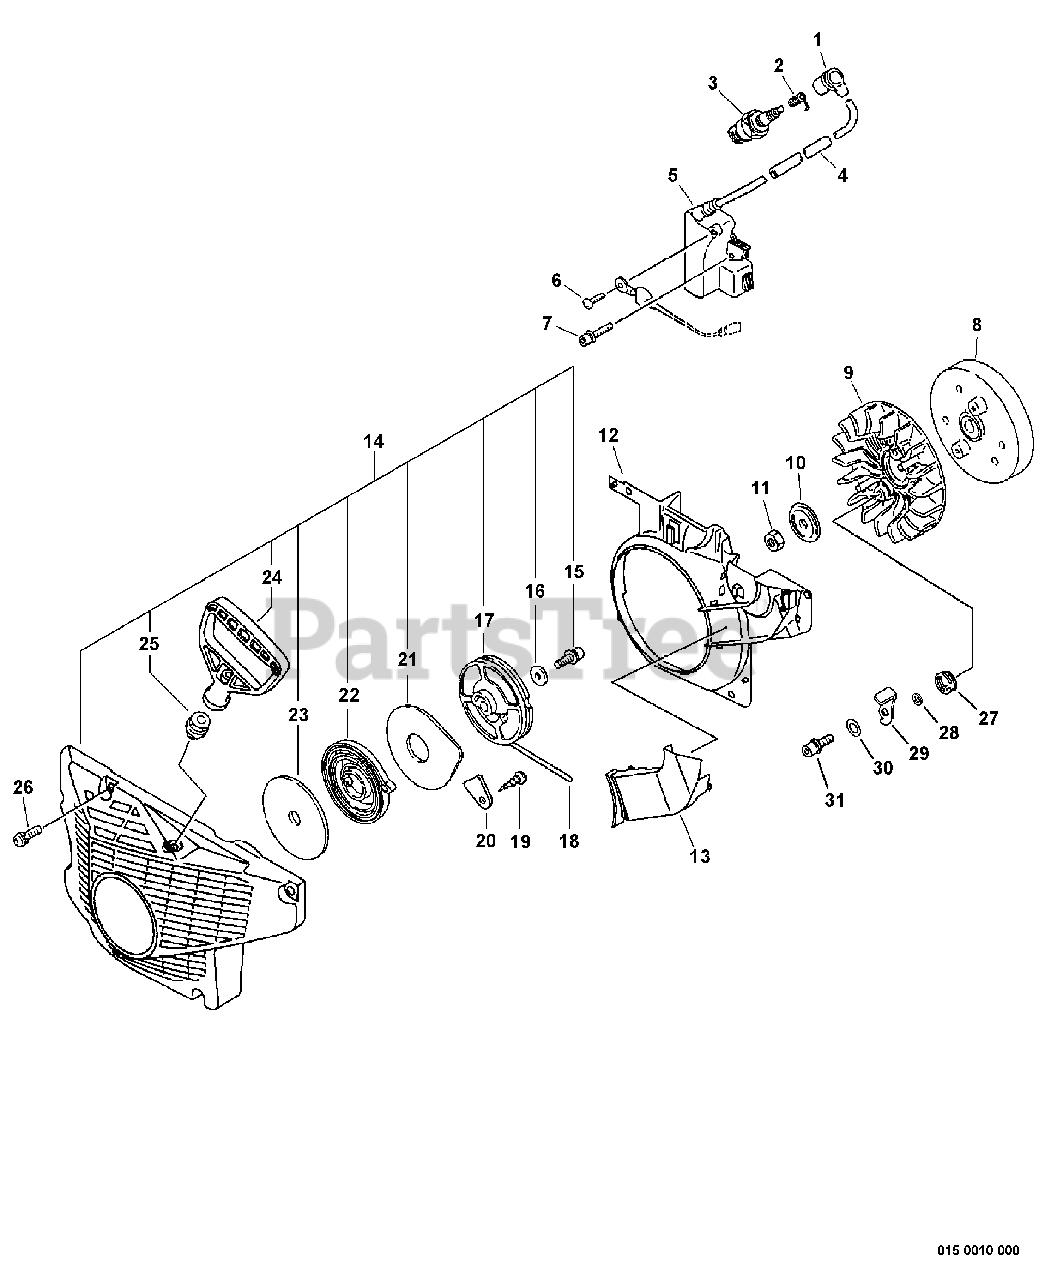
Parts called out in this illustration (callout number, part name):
1	CAP, SPARK PLUG
2	TERMINAL, SPARK PLUG
3	SPARK PLUG - BPM7A
3	SPARK PLUG - BPMR7A
5	COIL, IGNITION
6	SCREW 4×8
7	BOLT 4×20
8	FLYWHEEL
10	WASHER 8.2×31×0.8
12	COVER, FAN
13	DUCT, AIR
14	STARTER ASSY
15	BOLT 5×14
16	WASHER 5.5×12×0.8
17	REEL, ROPE
18	ROPE, STARTER 4.0×950
19	SCREW 4×8
20	PLATE, EYE
21	PLATE, STARTER
22	SPRING, RECOIL
23	PLATE, STARTER
24	GRIP, STARTER
25	GUIDE, ROPE
26	BOLT 5×20
27	SPRING, RETURN
28	COLLAR 5
29	PAWL, STARTER
30	WASHER 5.5×12×0.8
31	BOLT 5×18
